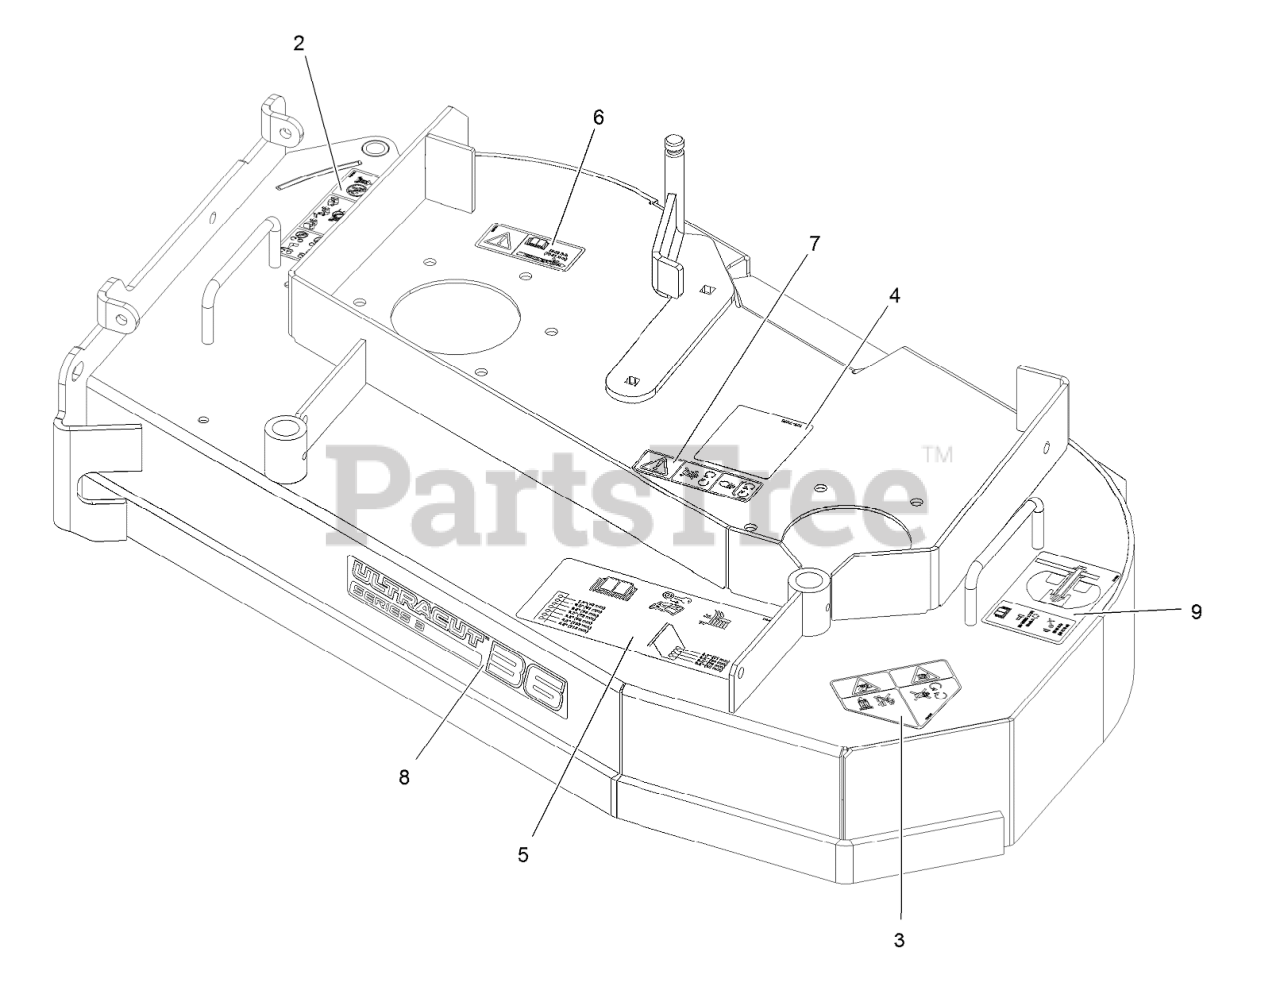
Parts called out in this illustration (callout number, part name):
2	DECAL-WARNING THROWN OBJ
3	DECAL-DANGER
4	DECAL-ROUTING, BELT
5	DECAL-ANTI-SCALP
6	DECAL-BOLT TORQUE
7	DECAL-COVER, MISSING
8	DECAL-ULTRACUT 36 SERIES
9	DECAL-ROLLER MOUNTING
